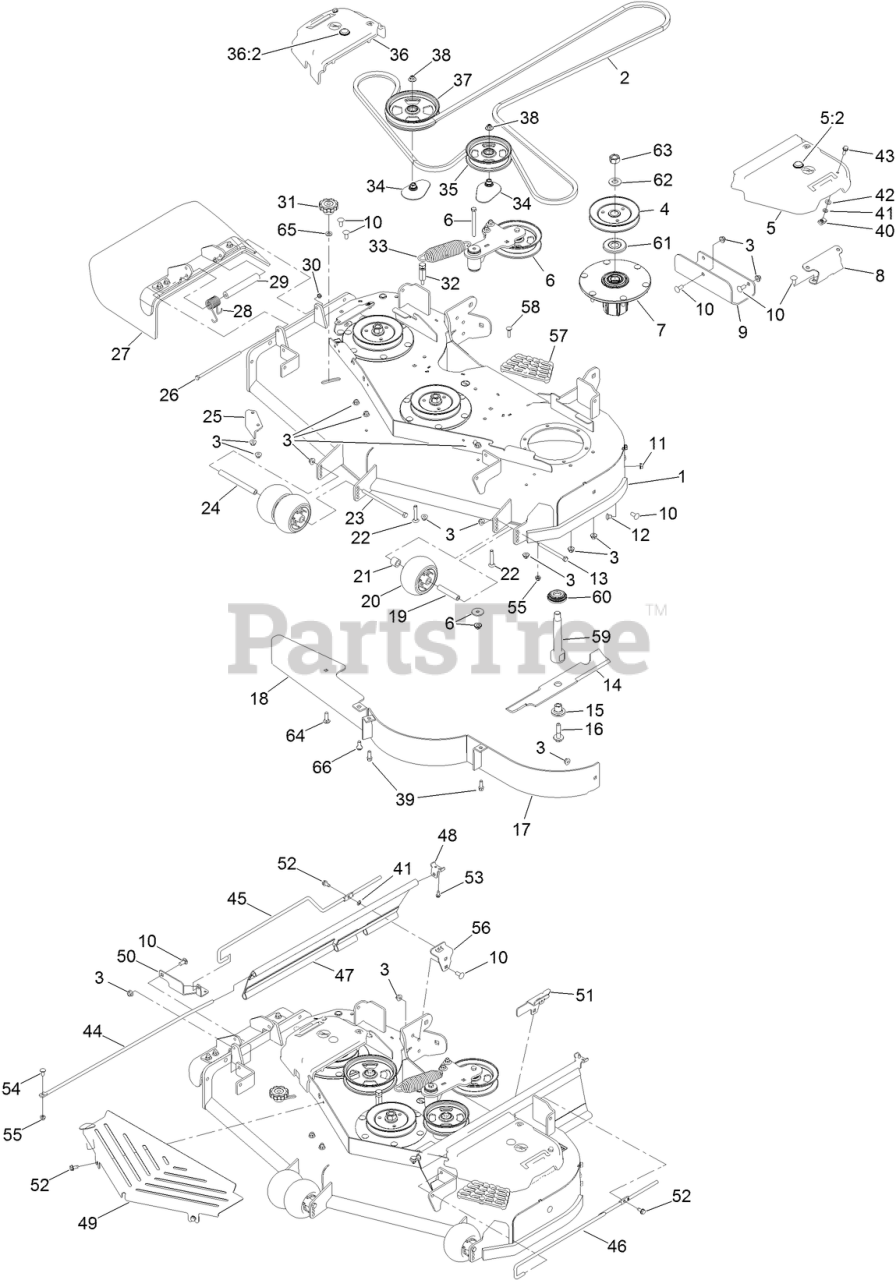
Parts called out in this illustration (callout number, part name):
1	DECK DECAL ASM
2	BELT-V
2	PLUG-PLASTIC
3	NUT-HF, NI
4	SHEAVE,BLADE DRIVE 5.91
5	LH BELT COVER ASM
5:2	PLUG-PLASTIC
6	IDLER ARM ASM
7	SPINDLE ASM
8	BRACKET-COVER, BELT
9	PLATE-SKID
10	SCREW-CARR
11	NUT-HHF, WHIZ
12	SCREW-CARR
13	SCREW-HH
14	BLADE-16.50 HIGH FLOW
15	BUSHING-HEX
16	SCREW-SEMS
18	PLATE-BAFFLE, FORMED
19	TUBE-SPANNER
20	ROLLER-SCALP, ANTI
21	TUBE-SPACER
22	BOLT-CARR, SHORT NECK
23	SCREW-HH
24	SPACER-WHEEL
25	BAFFLE-DISCHARGE
26	SCREW-HH
27	RUBBER DEFLECTOR ASM
28	SPRING-TORSION
29	SPACER
30	NUT-LOCK, NI
32	ANCHOR-SPRING, TALL
33	SPRING-EXTENSION
34	SPACER-PULLEY
35	PULLEY-IDLER,FLAT
36	RH BELT COVER ASM
36:2	PLUG-PLASTIC
37	PULLEY-IDLER, FLAT
38	NUT-FLANGE, NI
40	NUT-U
41	NUT-PUSH
42	WASHER-THRUST
43	SCREW-HHF
44	ROD-SUPPORT, UPPER
45	ROD-SUPPORT, LOWER (RH)
46	ROD-SUPPORT, LOWER (LH)
47	GUARD-SIDE
48	BRACKET-MOUNTING, UPPER
49	SHIELD-FRONT
50	BRACKET-MOUNTING, FRONT
51	BRACKET-MOUNTING, REAR (LH)
52	SCREW-HWHTF
53	SCREW-HWH
54	SCREW-CARR
55	NUT-HF, NI
56	BRACKET-MOUNTING, REAR (RH)
57	STEP-DECK
58	SCREW-CARR
59	SHAFT-SPINDLE
60	GUARD-BOTTOM
61	GUARD-BEARING, TOP
62	WASHER
63	NUT-HEX
64	BOLT-CARR
65	WASHER-HARDENED
66	BOLT-SHOULDER
